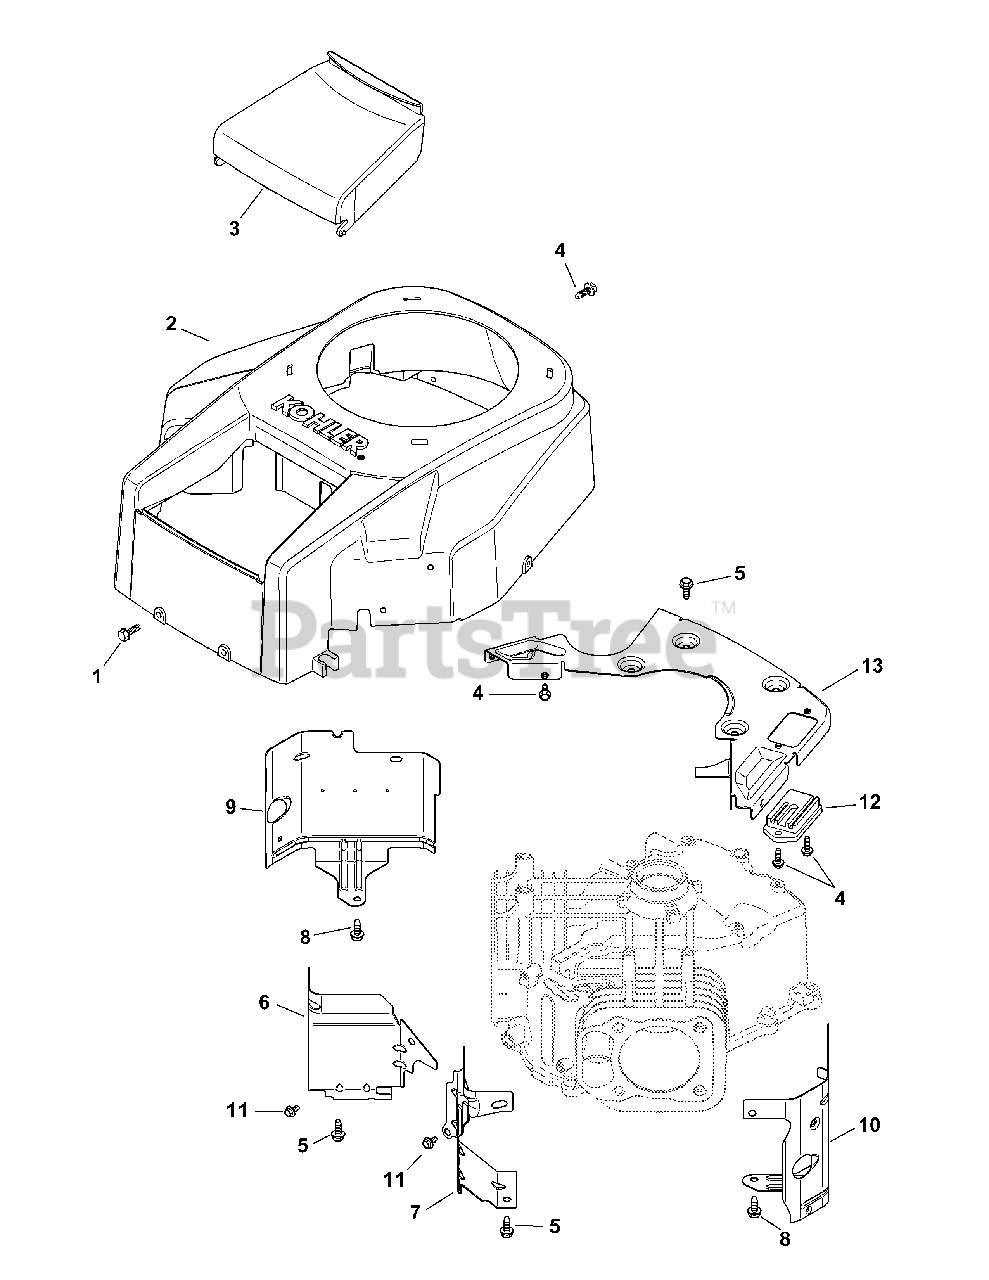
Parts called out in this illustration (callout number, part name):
1	Tap Screw, M6 x 1.7 x 18
2	Housing Blower Kit
3	Air Cleaner Cover
4	Flg. Thd. Frm. Screw, M5 x 0.8 x 16
5	Flg. Thd. Frm. Screw, M6 x 1.0 x 16
6	Valley Baffle - #1 Cylinder
7	Valley Baffle - #2 Cylinder
8	Flng. Thd. Frm. Screw, M6 x 1.0 x 10
9	Cyl Barrel Baffle - #1 Side
10	Cyl Barrel Baffle - #2 Side
11	Flg. Thd. Frm. Screw, M5 x .8 x 10
12	Regulator/Rectifier
13	Backing Plate Kit
